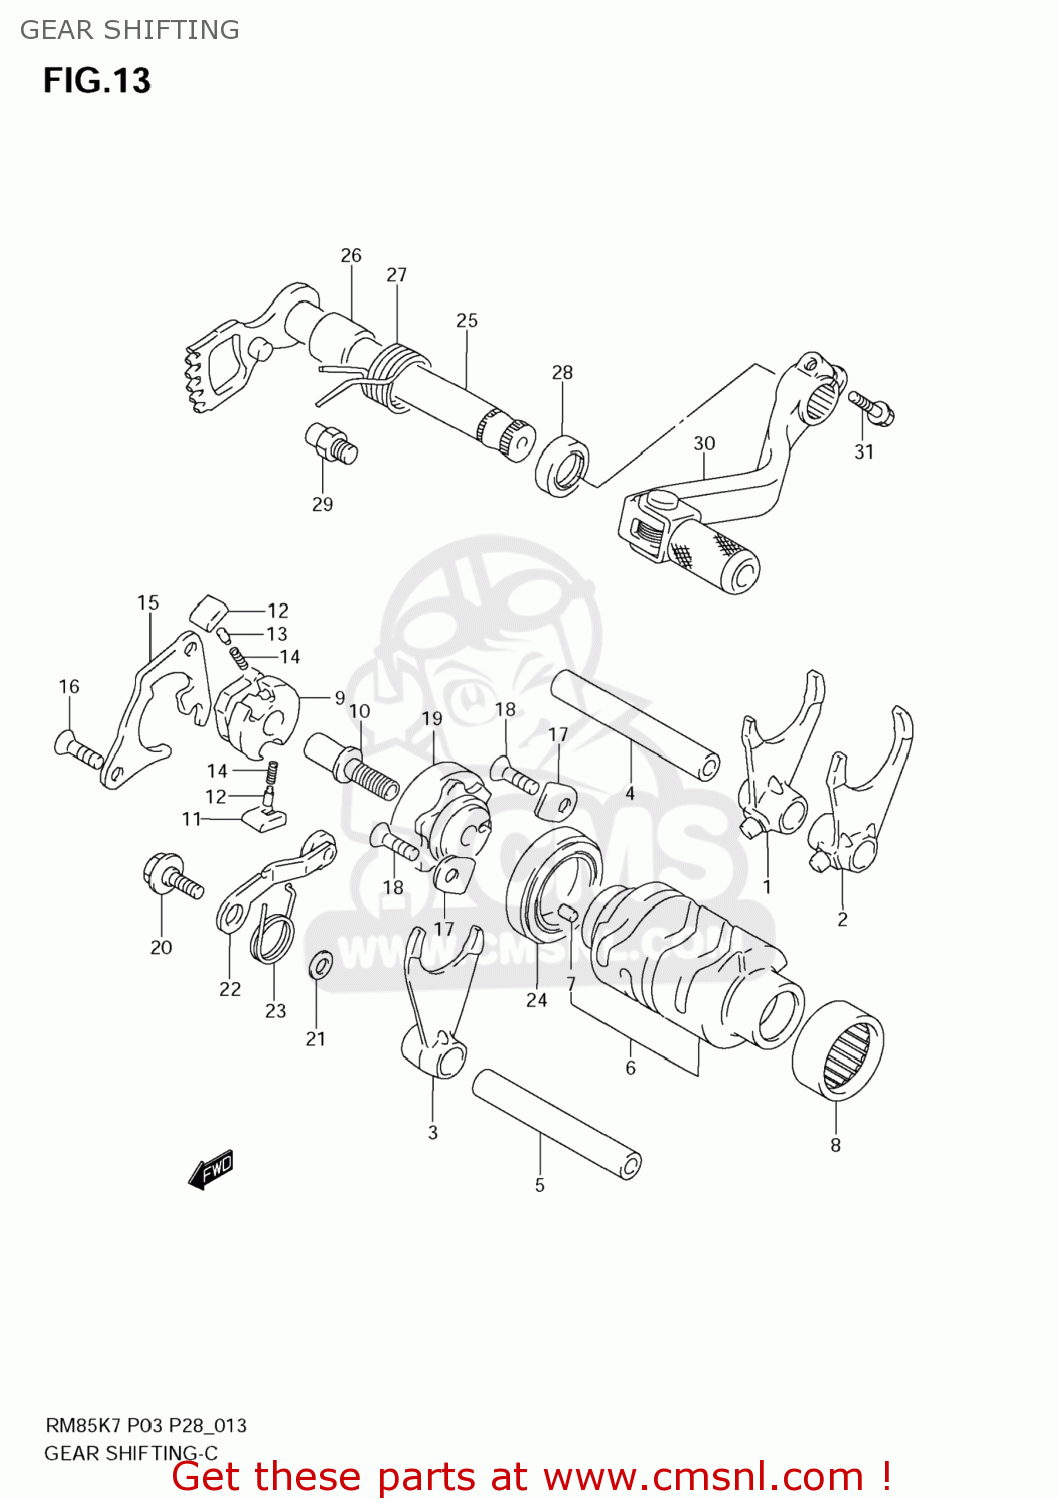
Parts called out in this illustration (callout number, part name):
1	FORK,GEAR SHIFT NO.1
2	FORK,GEAR SHIFT NO.2
3	FORK,GEAR SHIFT NO.3
4	SHAFT,GEAR SHIFT FORK NO.1
5	SHAFT,GEAR SHIFT FORK(L:60)
6	CAM,GEAR SHIFT
7	PIN
8	BEARING(25X32X12)
9	GEAR,GEAR SHIFT CAM DRIVEN
10	PIN,SHIFT CAM DRIVEN GEAR
11	PAWL,GEAR SHIFT NO.1
12	PAWL,GEAR SHIFT NO.2
13	PIN
14	SPRING
15	LIFTER,GEAR SHIFT POLE
16	SCREW(6X12)
17	RETAINER,COUNTER BEARING,R
18	SCREW(6X12)
19	PLATE,SHIFT CAM STOPPER
20	BOLT(6X14.3)
21	WASHER
22	STOPPER,SHIFT CAM
23	SPRING,SHIFT CAM STOPPER
24	BEARING
25	SHAFT,GEAR SHIFT
26	SPACER(14X20X17.5)
27	SPRING
28	SEAL,OIL(14X22X6)
29	STOPPER,GEAR SHIFT ARM
30	LEVER ASSY,GEAR SHIFT
31	BOLT
